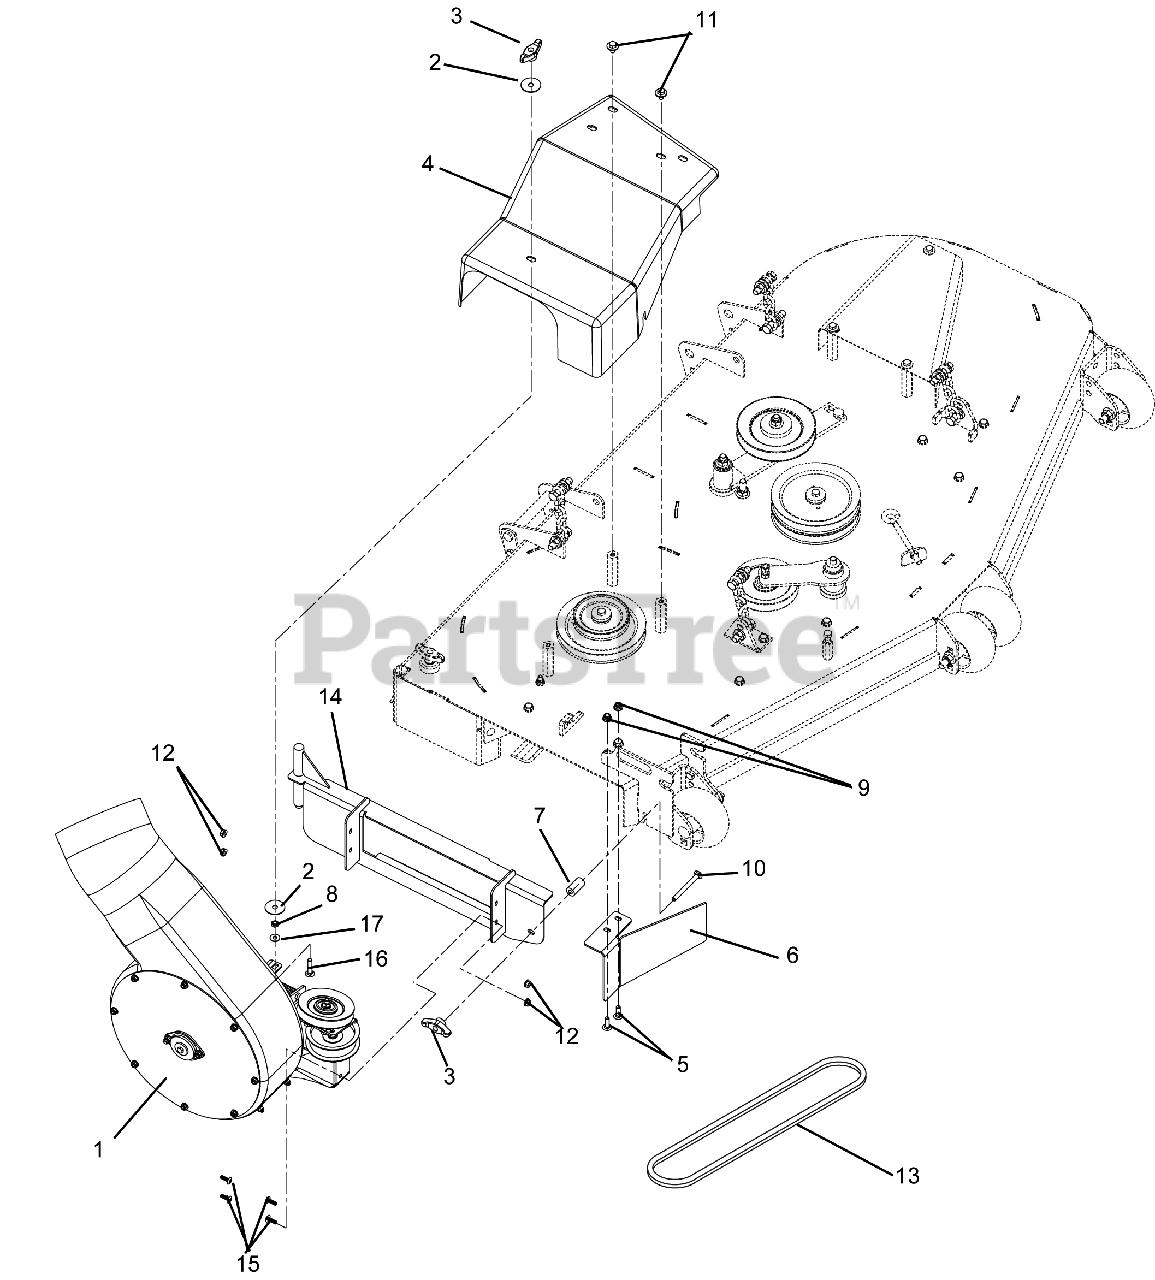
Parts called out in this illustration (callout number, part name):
1	BLOWER (SERVICE ASSEMBLY)
2	WSHR-FL-STL .380X1.50X.062 YWZ
3	KNOB - WING .312-18 UNC
4	GUARD, 52"-60"HD BAGGER BELT
4	GUARD,44"-48"CZ-HD BAGGER BELT
5	@BLT-RHDSSQNK .31-18X1.00 G5YZ
6	60"HD BAGGER BAFFLE - BLACK
7	SPACER, CZ-HD BAGGER
8	NUT- JAM .312-18 YWZC
9	@NUT-LK-NYL-FLG .31-18 YWZC
10	@BLT-RDHDSQNK .38-16X1.00 G5YZ
11	KNOB,WING STUD 5/16-18 X .75
12	@NUT-LK-TOP-FLG .25-20 YWZC
13	V-BELT, 4L-RAW EDGE
13	V-BELT, 4L-WRAPPED
13	V-BELT, HA-WRAPPED
14	60"HD BAG PUMP MTG BRKT WMT-BL
14	52"HD BAG PUMP MTG BRKT WMT-BL
14	48"CZ BAG PUMP MTG BRKT WMT-BL
14	44"CZ BAG PUMP MTG BRKT WMT-BL
15	SCR-MCH .25-20X.75 TXTR YWZC
16	@BLT-RDHDSQNK .31-18X1.50 G5YZ
17	@WSHR-FL-STL.312X.734X.065 YWZ
